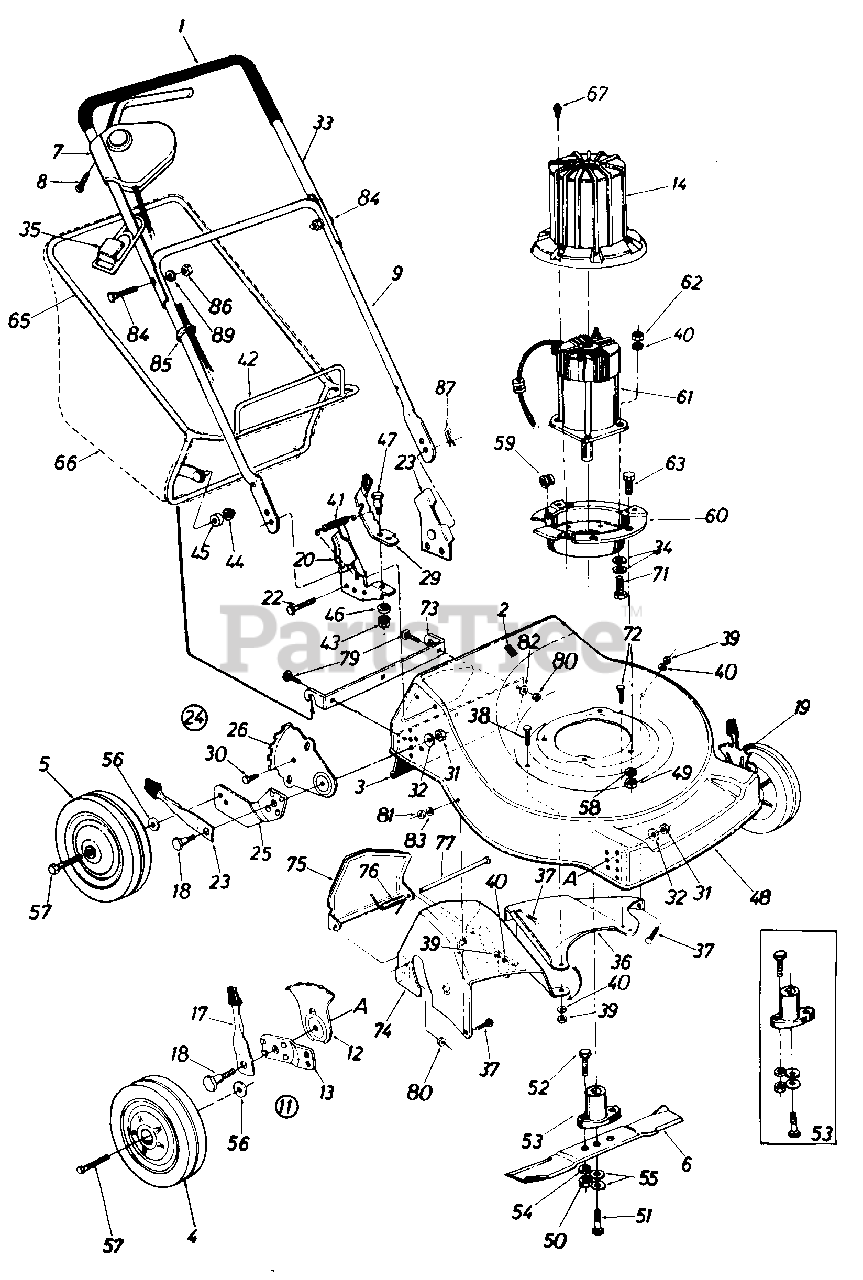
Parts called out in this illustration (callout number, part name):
3	Rear Flap Ass'y.
4	Front Wheel Ass'y. Comp. 7 x 1.75
5	Rear Wheel Ass'y. Comp. 8 x 1.75
6	20" Blade
7	Control w/Cord
8	Truss Mach. AB-Tap. Scr.
9	Lower Handle
11	Front Height Adj Ass'y. R.H.
12	Front Index Plate
13	Front Pivot Bar
14	Shroud
17	Spring Lever w/Knob
18	Shoulder Bolt .50" Dia. x .375
19	Front Height Adj. Ass'y. L.H.
20	Handle Brkt. Ass'y. R.H.
22	Hex Wash. Hd. AB-Tap Scr. 1/4" X .62" Lg.
23	Spring Lever w/Knob
24	Rear Height Adj. Ass'y. R.H.
25	Rear Pivot Bar R.H.
26	Rear Index Plate
29	Lock Lever
30	Hex Wash. Tap Scr. 1/4 x .62" Lg.
31	Hex Nut 3/8-16 Thd.
32	L-Wash. 3/8" I.D.
33	Upper Handle
34	Fl-Wash. 3/8" I.D. x 1.0" 0. D.
35	Restraint
36	Rear Chute Baffle L.H.
37	Carr. Bolt 1/4-20 x .501' Lg.
38	Hex Bolt 1/4-20 x .88" Lg.
39	Hex Nut 1/4-20 Thd.
40	L-Wash. 1/4" I.D.
41	Extension Spring
44	Push Cap 3/8" Rod
45	Plastic Roller
46	L-Wash. 5/16" I.D.
47	Shoulder Bolt
50	Hex Nut 5/16-24 Thd.
51	Hex Bolt 5/16-24 x .75" Lg.
52	Hex Bolt 5/16-24 x 1.00" Lg.
53	Blade Adapter Kit
54	L-Wash. 5/16" I.D.
55	Bell-Wash. .345" I.D. x .88" O.D.
56	Bell-Wash. .400" I.D. x .88" O.D.
57	Shld. Scr. .498" Dia. x 1.45"
58	L-Wash. 3/8" I.D.
59	Cord Restraint
60	Adapter Plate
62	Hex Jam Nut 1/4-20 Thd.
63	Hex Bolt 3/8-16 x 1.00" Lg.
65	Grass Catcher Upper Frame
66	Grass Bag
67	Hex Wash. Hd. F-Tap Scr. #10-32 x .25" Lg.
71	Hex Bolt 1/4-20 x 1.00" Lg.
72	Hex Wash. Hd. Self-Tap Scr. 1/4-20 x .75" Lg.
73	Grass Catcher Hitch Brkt.
74	Rear Chute Baffle R.H.
75	Chute Door
76	Torsion Spring
77	Hinge Pin .25" Dia. x 7.25" Lg.
79	Carr. Bolt 1/4-20 x .75" Lg.
80	Hex Sems Nut 1/4-20 Thd.
81	Hex Nut 1/4-20 Thd.
82	Fl-Wash. .281" I.D. x 1.25" O.D.
83	L-Wash. 1/4" I.D.
84	Curved Carr. Bolt 5/16-18 x 1.38" Lg.
85	Cable Tie
86	Hex Nut 5/16-18 Thd.
87	Hairpin Cotter
89	L-Wash. 5/16" I.D.
